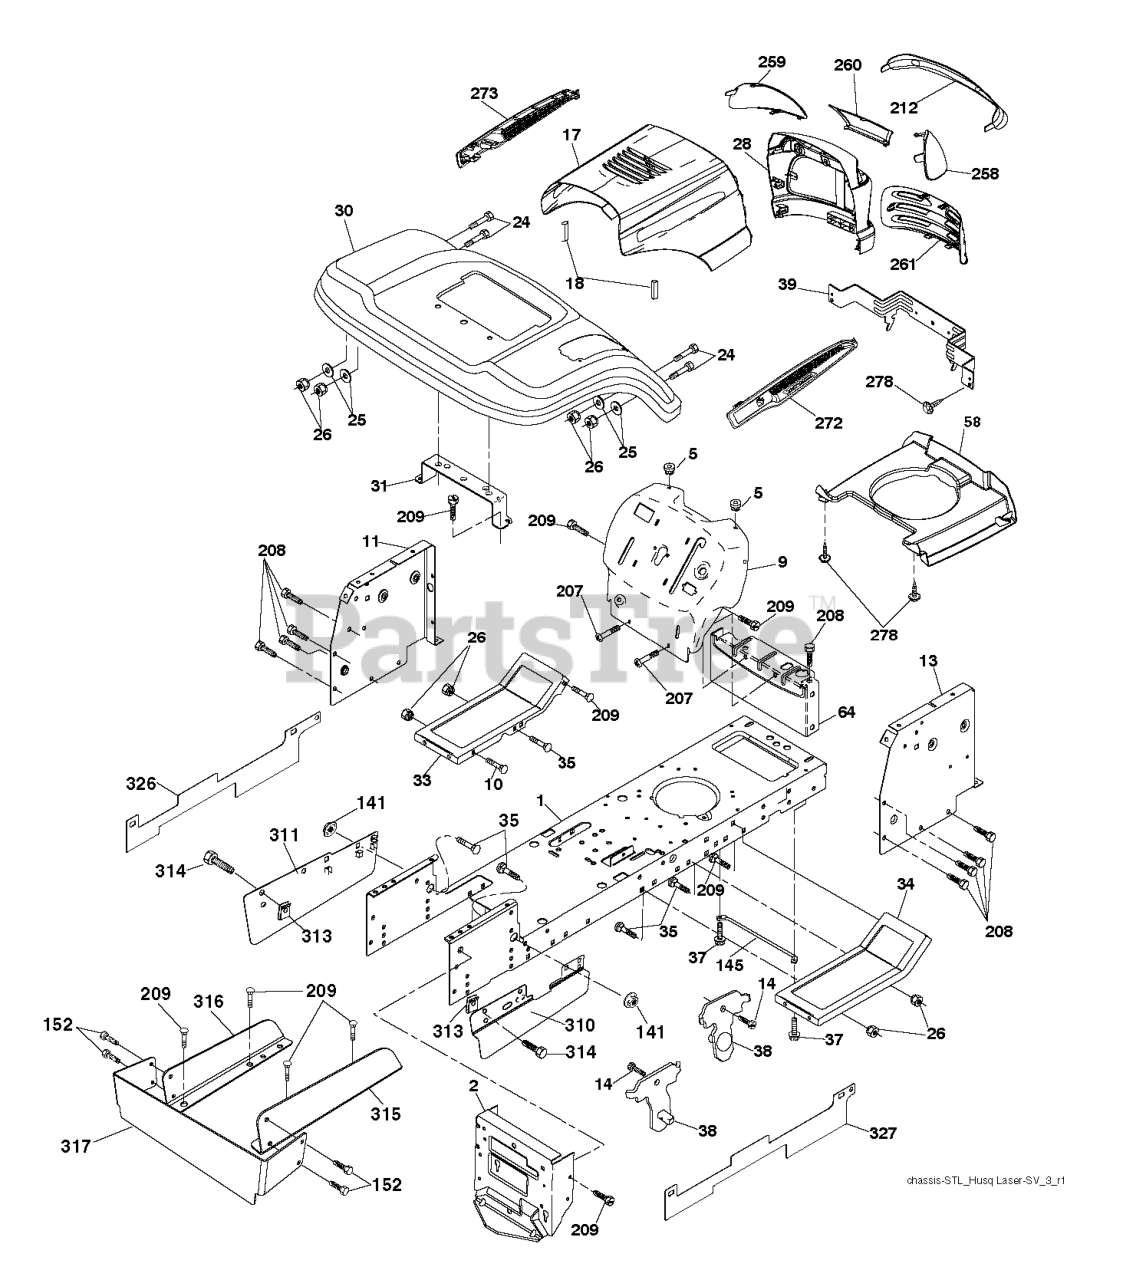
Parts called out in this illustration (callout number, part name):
1	CHASSIS STAMPING
2	DRAWBAR, 12GA
5	BUMPER.RUBBER.HOOD
9	DASH.SLKSCR.SL.PL.C.NA.NHMHUS
10	BOLT D
11	PANEL.DASH.LH.LTX
13	PANEL DASH RH
14	SCREW LT
17	HOOD.PNT.LASER.SV.LT.668
18	BUMPER.HOOD.LARGE.1.75"
24	BOLT
25	WASHER
26	NUT
28	GRILLE.HUSQ.LASER.LT.668
30	FENDER.PNT.LTST.W/S.N/C.668ROS
31	BRACKET FENDER
33	FOOTREST.LH.BLACK
34	FOOTREST.RH.BLACK
35	BOLT
37	Screw 5/16-18 x 1/2 Hex, Self Tapping 5/16-18 x 1/2
38	BRACKET.ASM.PIVOT.MOWER.REAR
39	BRACKET PIVOT
64	DASH LOWER
141	NUT LOCK FLG 3/8-16 UNC
145	ROD.PIVOT.HOOD
152	SCREW
207	SCREW, 5/16-18 X 1/2
208	SCREW 3/8-16X1/2
209	SCREW, 3/8-16X3/4
212	INSERT.LENS.REFLECTIVE
258	LENS LH
259	LENS LH
260	COVER.LENS.HUSQ.LASER.LT.498
261	INSERT.GRILLE.HUSQLASER.LT.498
272	VENT.HOOD.LASER.III.SD.RH
278	SCREW.#10 X 0.750.BOS
314	SCREW.1/4-20X5/8
